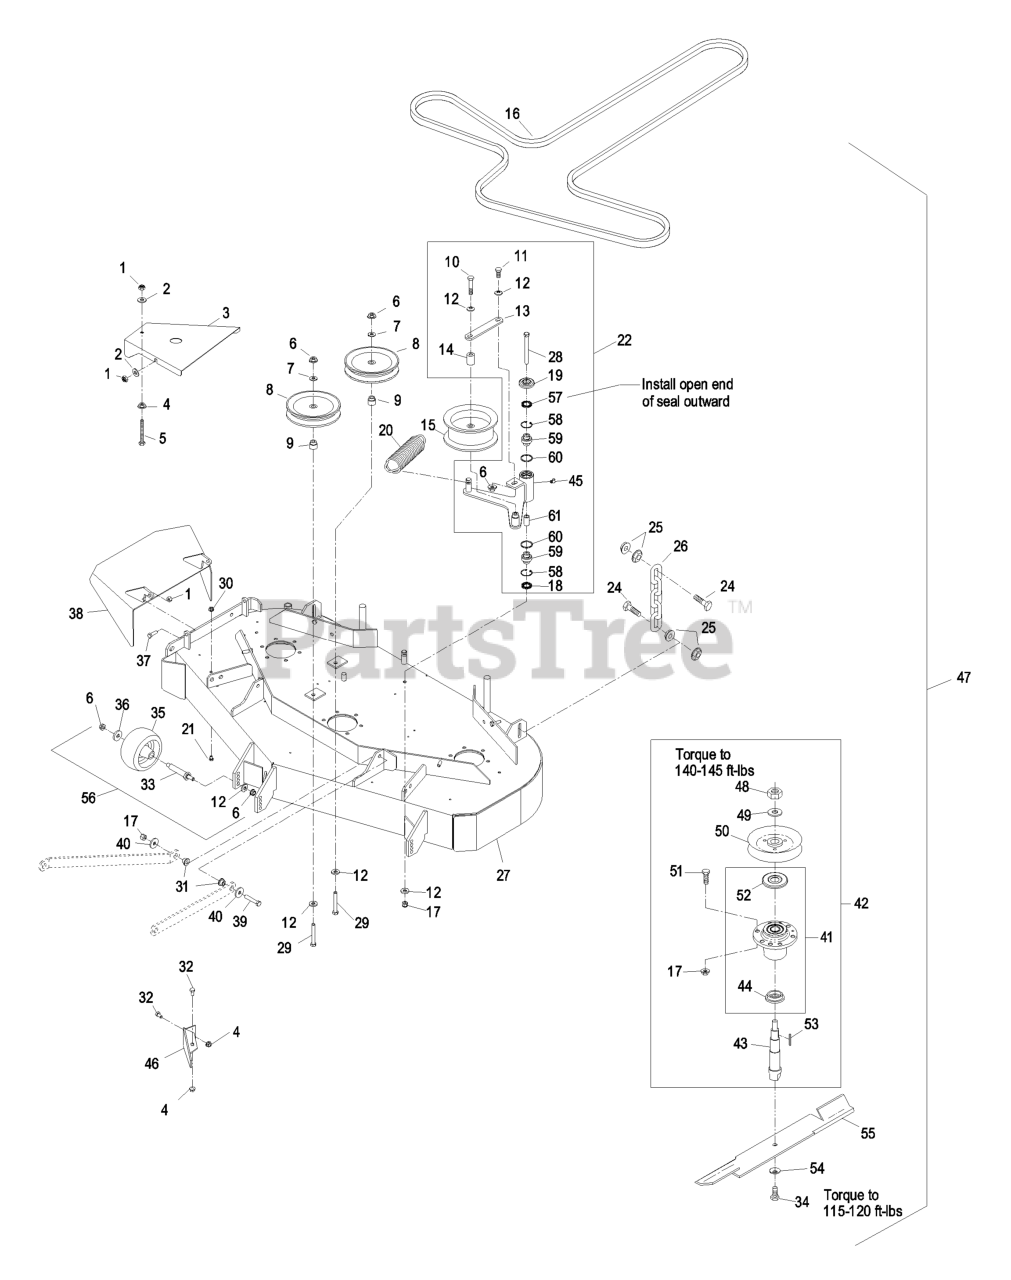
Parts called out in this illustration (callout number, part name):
1	NUT-LOCK, NI
2	WASHER-FLAT
3	SHIELD,BELT
5	BOLT,TAP HH
6	NUT-HHF, WHIZ
7	WASHER-FLAT
8	PULLEY-IDLER
9	BUSHING-IDLER
10	SCREW-HH
11	SCREW-HH
12	WASHER-BELLEVILLE
13	PLATE,GUIDE BELT (PLTD)
16	BELT - V, B
17	NUT-LOCK, NI
18	SEAL-LIP, DOUBLE
19	GUARD-TOP
21	SCREW-HH
22	KIT,DECK IDLER LHP/LCT
23	BUSHING-PIVOT, IDLER
24	SCREW-CAP, HH
26	CHAIN-LIFT, DECK
27	ASM,DECK W/DECALS LCT44
28	SCREW-HH
29	SCREW-HH
31	SPACER-STRUT
32	SCREW-HH
34	SCREW-CAP
35	ROLLER-SCALP, ANTI
37	SCREW-HH
38	WLD,CHUTE 48
39	SCREW-HH
41	KIT, CUTTER HOUSING
42	ASM, CUTTER HSG LCT 44
43	SPINDLE,SHAFT
44	SPACER-GUARD, BOTTOM
45	FITTING-GREASE, 90 DEG
47	Asm, Deck Complete (44")
48	NUT-HH
50	SHEAVE,W/HUB
51	SCREW-HH
52	GUARD-BEARING, TOP
53	KEY-RECTANGLE
54	WASHER-SPRING
57	SEAL-LIP, SINGLE
58	RING-SNAP
59	BEARING-SPHERICAL
